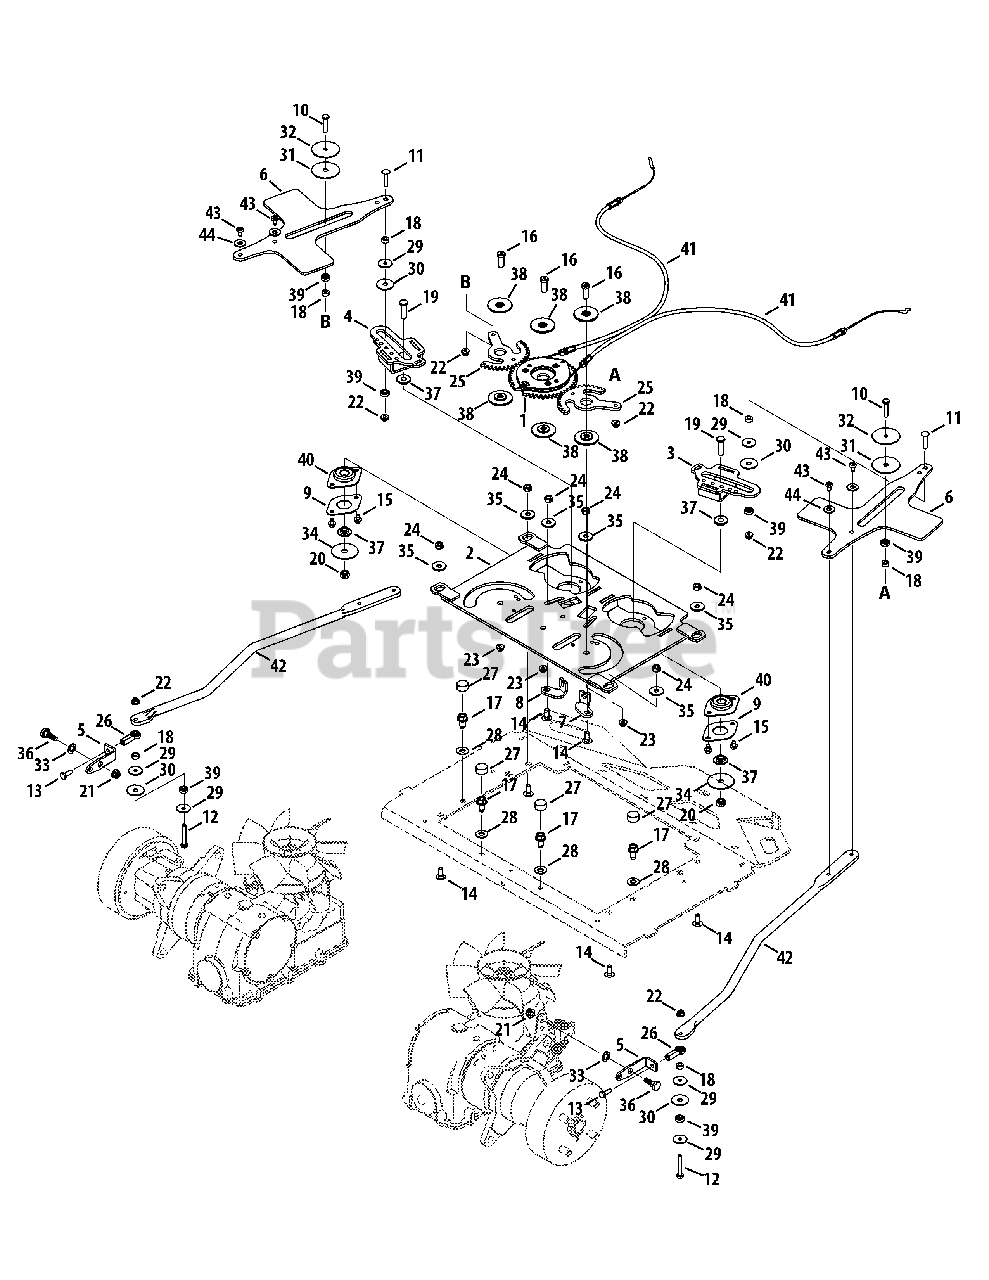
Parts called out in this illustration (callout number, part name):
1	Pump Control Gear
2	Pump Control Mounting Plate
3	Pump Control Cam Assembly, RH
4	Pump Control Cam Assembly, LH
5	Pump Control Bracket
6	Pump Steering Arm Actuator
7	Steering Cable Bracket
8	Steering Cable Bracket
9	Retainer Bearing Plate
10	Hex Cap Screw, 1/4-20 x 1.25
11	Carriage Screw, 1/4-20 x 1.25
12	Hex Cap Screw, 1/4-20 x 1.75
13	Hex Cap Screw, 1/4-28 x .75
14	Carriage Bolt, 5/16-18 x .75
15	Hex Flange Screw, 1/4-20 x .500
16	Socket Head Screw, 3/8-16 x 1.00
17	Screw, 3/8-16 x .75
18	Spacer, .256 x .500 x .240
19	Hex Cap Screw, 3/8-16 x 1.25
20	Nut, 3/8-16, Hexlock
21	Nut, 5/16-18, Flangelock
22	Nut, 1/4-20, Flangelock
23	Nut, 3/8-16, Flnagelock
24	Nut, 5/16-18, Hexlock
25	Yoke Steering Gear
26	Rod End, 1/4-28
27	Slide Cap
28	Washer, .406 x .875 x .059
29	Washer, .255 x 1.00 x .060
30	Washer, .355 x 1.25 x .060
31	Washer, .356 x 2.00 x .060
32	Washer, .260 x 2.00 x .060
33	Washer, .469 x .75 x .060
34	Washer, .406 x 1.92 x .060
35	Washer, .345 x 1.00 x .100
36	Shoulder Screw, .437 x .268, 5/16-18
37	Shoulder Spacer, .38 x 1.00 x .31
38	Shoulder Spacer, .853 x .385 x .100
39	Ball Bearing, .250 x .625
40	Ball Bearing, .625
41	Transmission Link Control Cable
42	Pump Control Rod
43	Shoulder Screw, .342 x .335, 1/4-28
44	Flat Washer, .344 x .688 x .065
